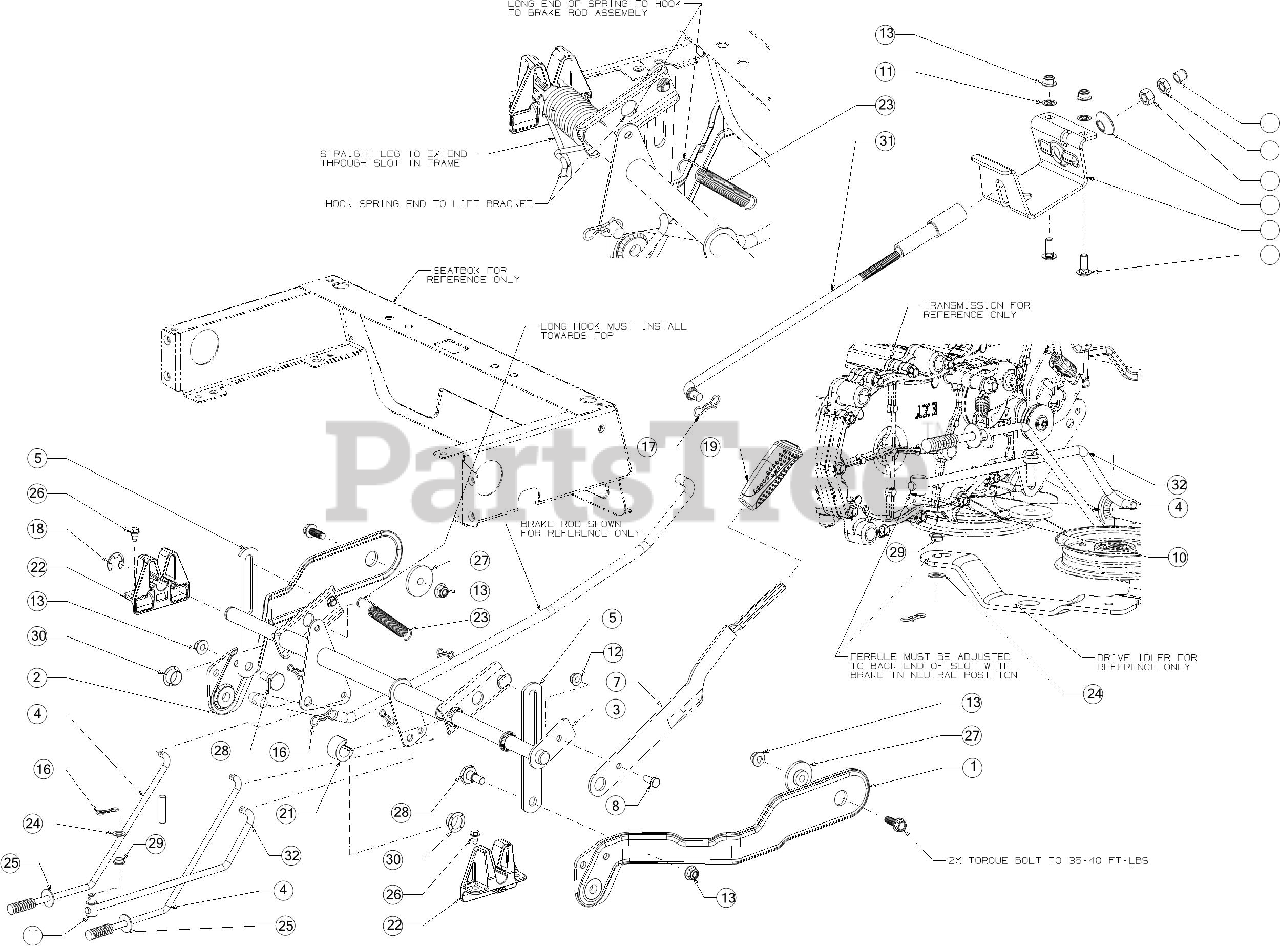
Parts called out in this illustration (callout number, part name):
1	DECK LIFT PLATE ASSEMBLY
2	DECK LIFT PLATE ASSEMBLY
3	DECK SHAFT ASSEMBLY
4	BRAKE ROD ASSEMBLY
5	LIFT LINK PLATE
6	ROD SUPPORT BRACKET
7	DECK LIFT HANDLE
8	SCREW 5/16-18 X .75 GR5
9	CARRIAGE BOLT 3/8-16 X 1.00 GR5
10	FERRULE 3/8-24 X .375
12	FLANGE LOCK NUT 5/16-18
14	HEX NUT NYLOK 1/2-13
15	HEX NUT
16	BOW TIE COTTER PIN 1/4-5/16
17	BOW TIE COTTER PIN
18	E-RING
20	LIFT ROD END CAP
21	SPACER: .76ID X .75
22	DECK LIFT BRACKET
23	EXTENSION SPRING .63 X 4.95
24	WASHER THRUST .375X.70X.030
25	FLAT WASHER 344X1.00
26	SHOULDER SCREW 1/4-20X.50 19PSH"
27	SHOULDER SPACER -S
28	SHOULDER SCREW
29	FLANGE BEARING
30	FLANGE BEARING .75 X 1.125 X .375
31	DECK FRONT LIFT ROD
32	DISENGAGEMENT BRAKE ROD
33	LIFT PIVOT CUP
34	SLEEVE .55 ID X 4.50 LG
